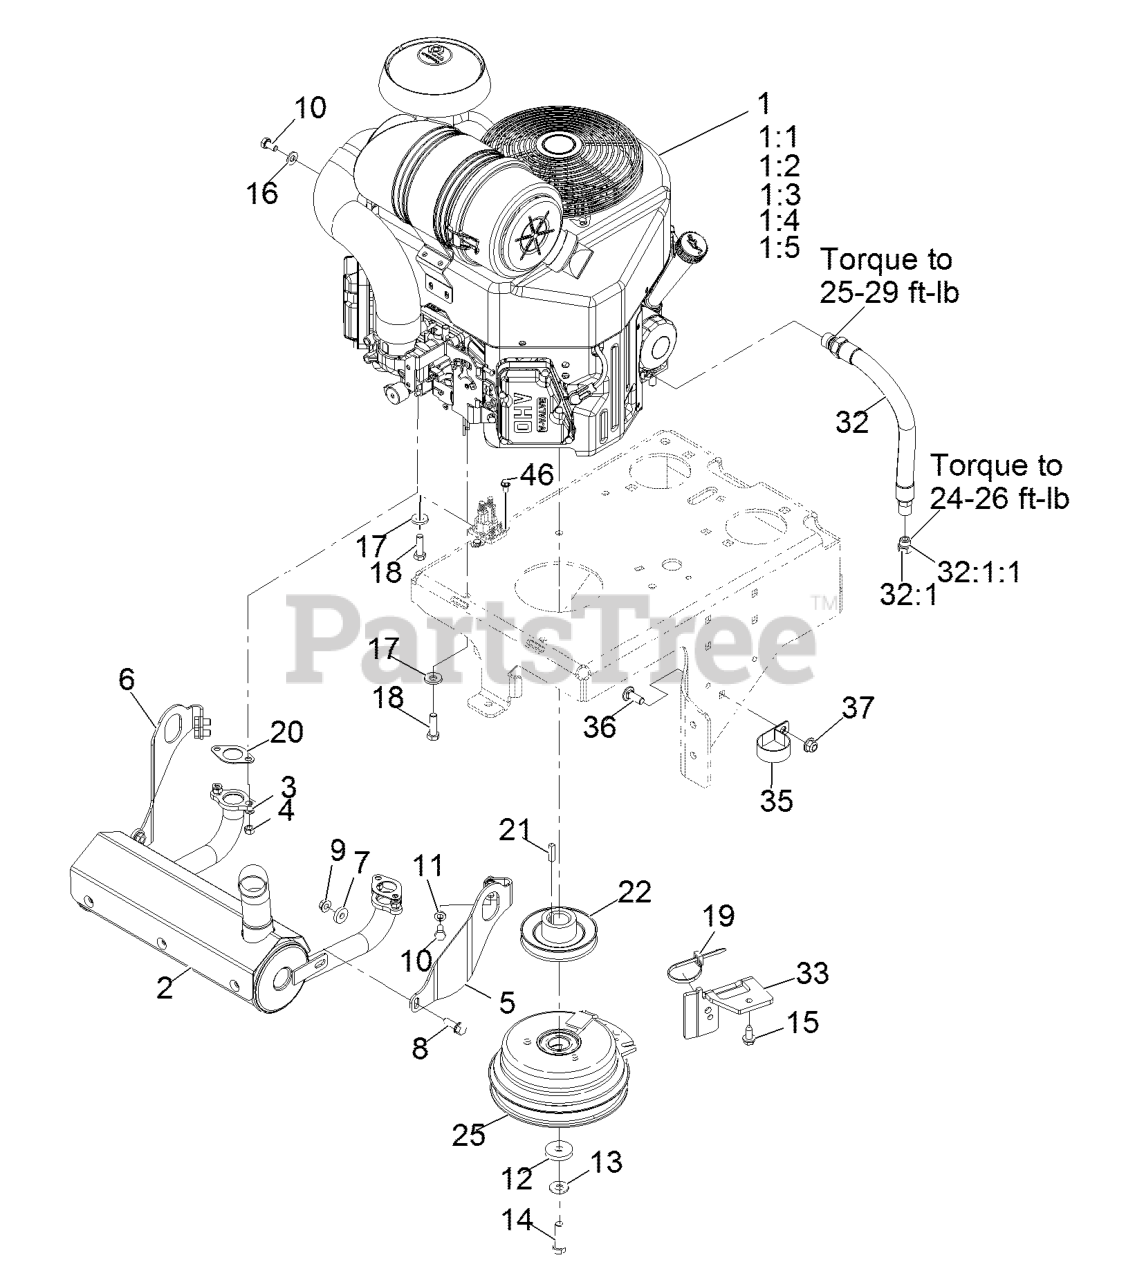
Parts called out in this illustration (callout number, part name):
1:1	FILTER-OIL
1:2	SPARK PLUG
1:3	ELEMENT-FILTER, AIR (OUTE
1:4	ELEMENT-FILTER, AIR (INNE
1:5	Filter-Fuel
2	MUFFLER, KAWASAKI, 22-26
3	WASHER-LOCK
5	BRACKET-MUFFLER MOUNT, LH
6	BRACKET-MUFFLER MOUNT, RH
8	SCREW-HHF
10	SCREW-HH
11	WASHER-LOCK
12	WASHER
13	WASHER-SPRING
14	SCREW-HH
15	Screw-HWH 5/16-18 X 3/4 Tf
16	WASHER-PLAIN
17	WASHER-BELLEVILLE
18	SCREW-HH
19	TIE-CABLE
20	GASKET-EXHAUST
25	CLUTCH-200 FT-LB, 1.125 B
32	ENGINE OIL DRAIN HOSE ASM
32:1	PLUG-HH
32:1:1	O-RING
33	BRACKET-ANCHOR, CLUTCH
35	CLAMP-R
36	SCREW-CARR
37	NUT-HF, NI
46	SCREW-HWH
